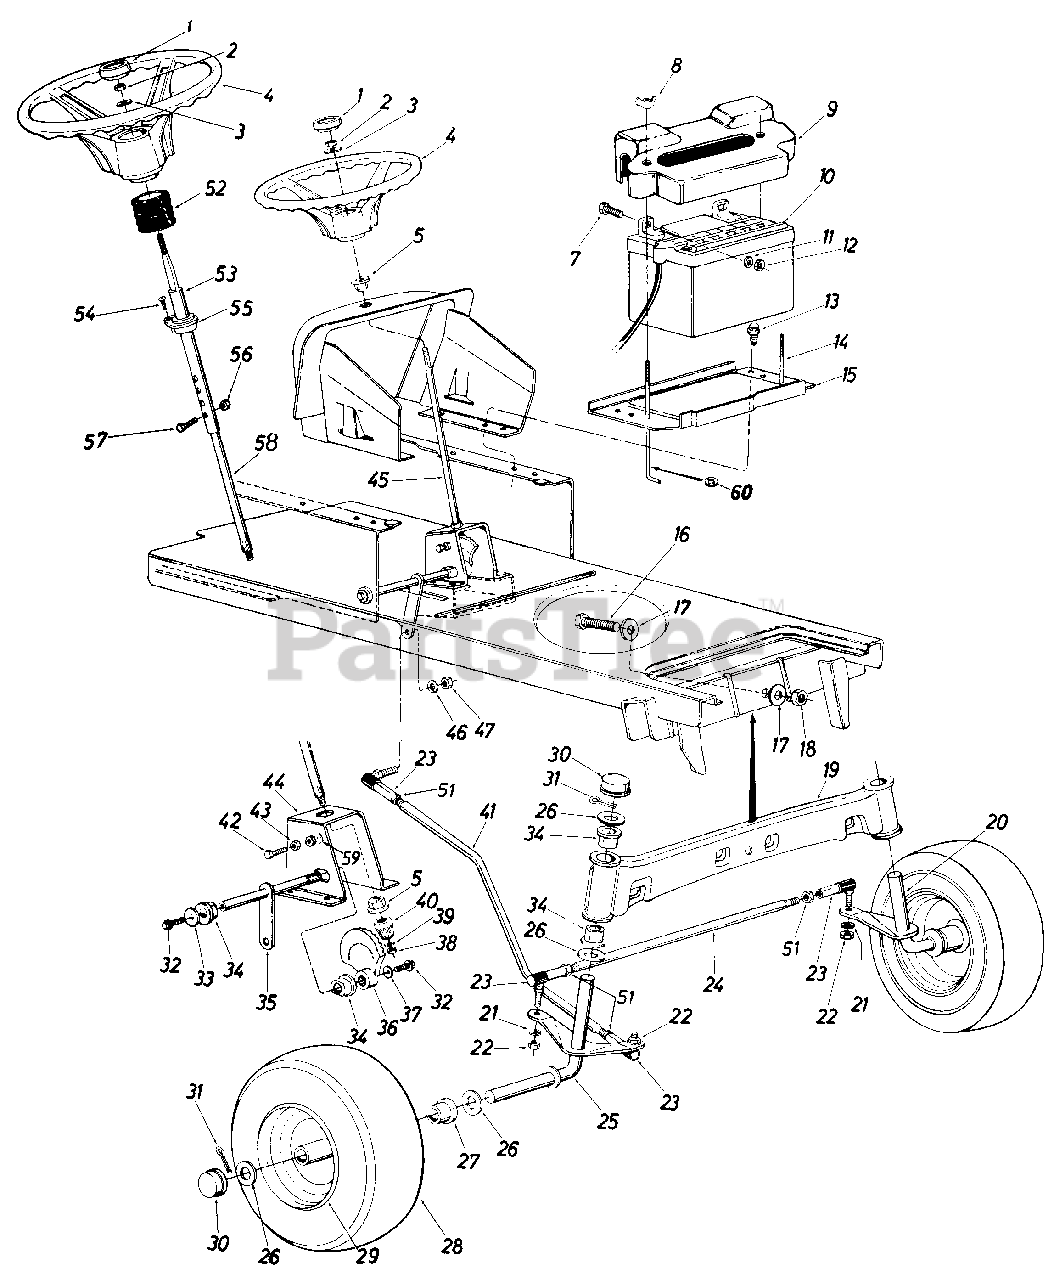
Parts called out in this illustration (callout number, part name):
1	Steering Wheel Cap
2	Hex Cent. L-Nut 5/16-24 Thd.
3	Bell-Wash. 5/16" I.D. x .87" O.D. x .060
4	Steering Wheel
5	Plastic Hex Bearing 518" I.D.
7	Hex Scr. 1/4-20 x .62" Lg.
8	Wing Nut Plastic 1/4-20 Thd.
9	Battery Cover
10	12-V Battery
11	L-Wash 1/4" I.D.
12	Hex Nut 1/4-20 Thd.
13	Hex Thd. Rolling Scr. 1/4-20 x.50" Lg.
14	Battery Hold Down Rod
15	Battery Plate
16	Hex Scr. 5/8-18 x 2.50" Lg.
17	Flat Wash. .66" I.D. x 2.25" O.D. x .17
18	Hex Cent. L-Nut 5/8-18 Thd.
19	Front Pivot Bar Ass'y.
20	Front Axle Ass'y.-L.H.
21	L-Wash. 3/8" Scr.
22	Hex Nut 3/8-24 Thd.
23	Ball Joint Ass'y.
24	Tie Rod
25	Front Axle Ass'y.-R.H.
26	Fl-Wash. .780 I.D. x 1.59 O.D.
27	Flange Bearing
28	Front Wheel Ass'y. Comp.
29	Front Wheel Rim Only
30	Dust Cover
31	Cotter Pin 5/32" Dia. x 1.00" Lg.*
32	Hex Scr. 3/8-24 x .75" Lg. Grade 5
33	Fl-Wash. 3/8 I.D. x 1.25 O.D. x .090
34	Flange Double "D" Brg. .753 I.D.
35	Steering Arm Shaft Ass'y.
36	Side Gear-Steering
37	Bell-Wash. 3/8" I.D.
38	Hex Cent. L-Nut 5/16-24 Thd.
39	Fl-Wash. 5/16" I.D. x .62 O.D. x .059
40	Pinion Gear-Steering
41	Drag Link
42	Hex Cap Scr. 3/8-16 x 1.25" Lg.
43	Hex Nut 3/8-16 Thd.
44	Steering Gear Sup. Ass'y.
45	Steering Shaft
46	L-Wash. 3/8" I.D.
47	Hex Nut 3/8-24 Thd.
51	Hex Jam Nut 3/8-24 Thd.
52	Steering Bellow
53	Upper Steering Shaft
54	Oval Hd. Cr.-Sunk Scr. #10 x 5/8" Lg.
55	Fl-Bearing .89" I.D. x 1.36" O.D.
56	Hex L-Nut 1/4-20 Thd.
57	Hex Bolt 1/4-20 x 1.31" Lg.
58	Lower Steering Shaft
59	Nylon Cap
60	Push Nut
